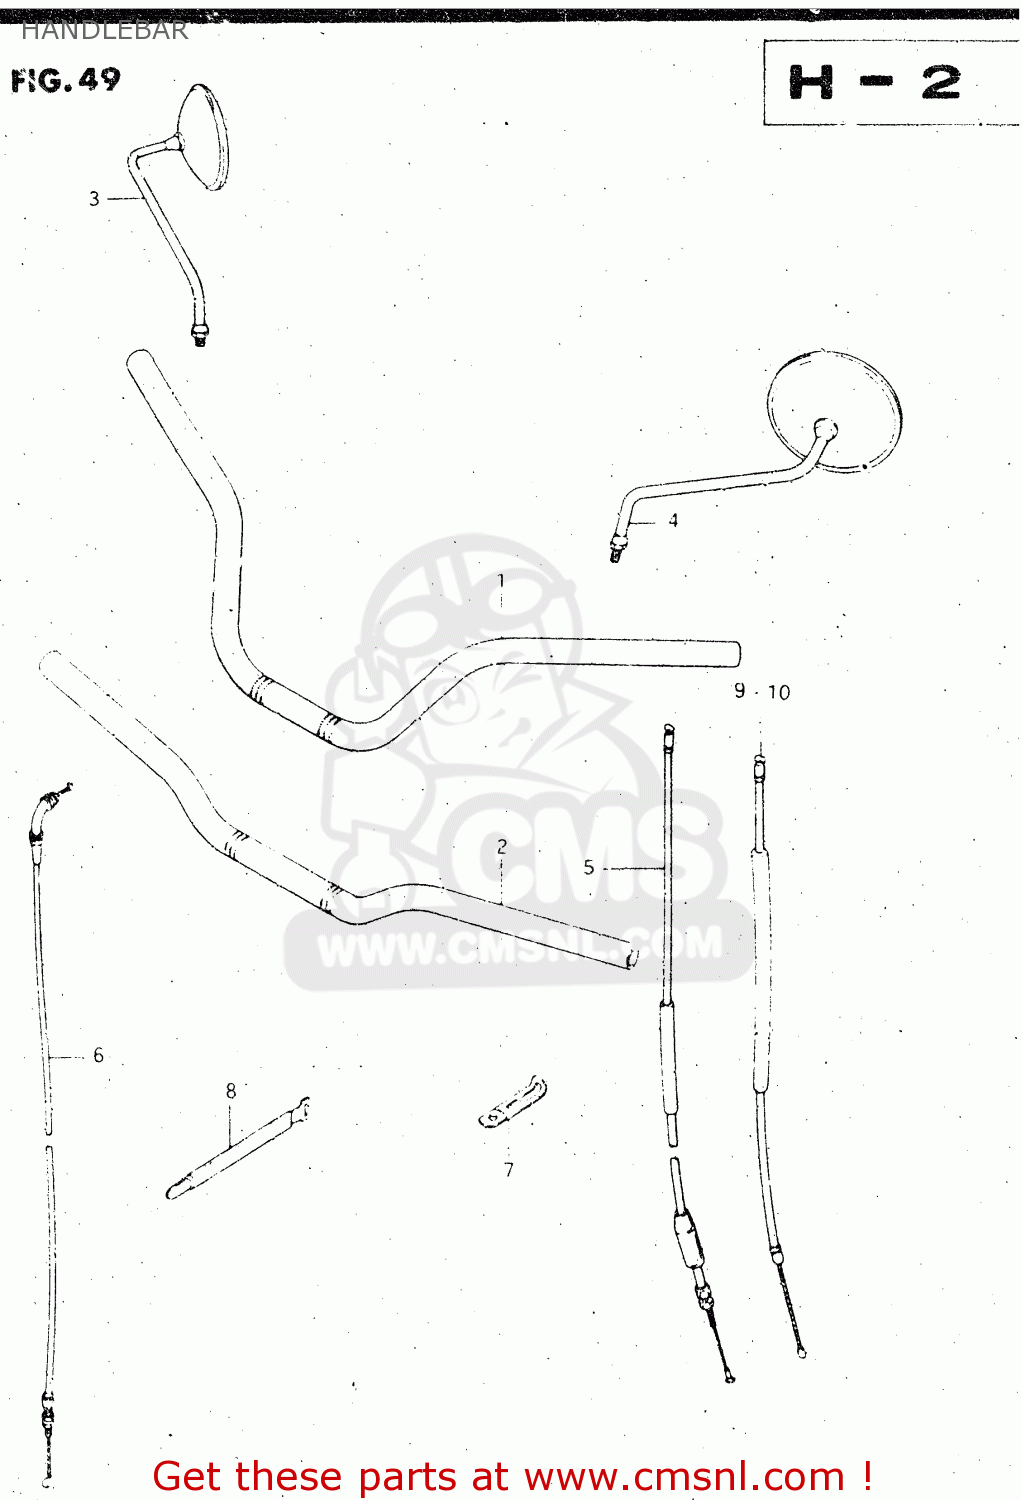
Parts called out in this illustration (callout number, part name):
1	HANDLEBAR (NERTRAL)
2	HANDLEBAR (FLAT)
3	MIRROR ASSEMBLY,REAR VIEW
4	MIRROR ASSEMBLY,REAR VIEW
5	CABLE ASSY,CLUTCH
6	CABLE ASSEMBLY,THROTTLE
7	CLAMP
8	CLAMP
9	CABLE ASSY,STA
10	CABLE, STARTER (FLAT)
